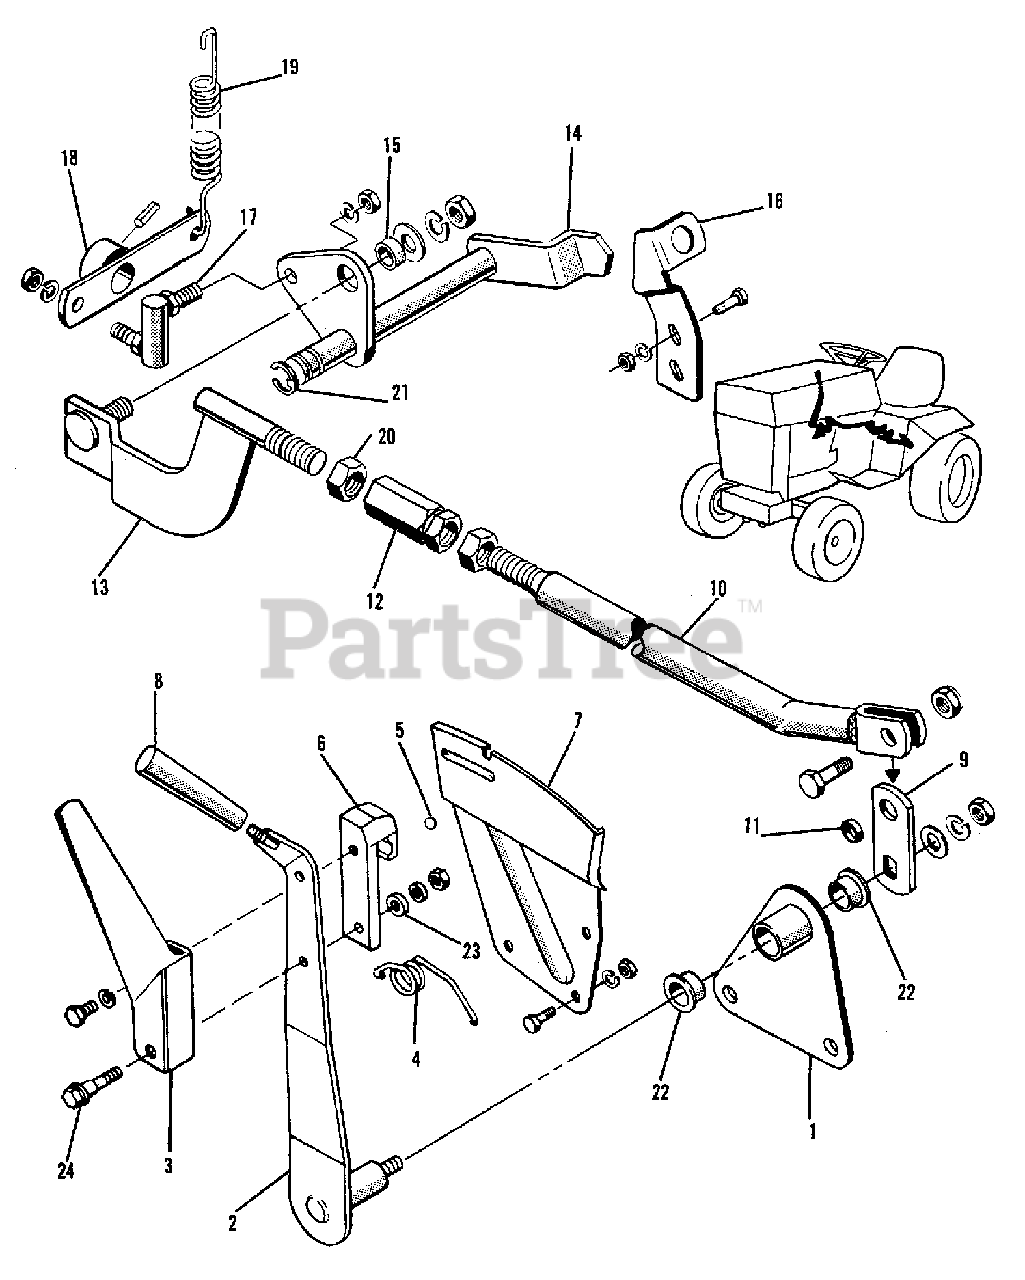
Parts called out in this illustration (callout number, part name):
1	BRACKET ASSEMBLY, Support
2	LEVER ASSEMBLY, Speed Control
2	WASHER, Plain, 3/8
2	LOCKWASHER, 3/8
2	NUT, 3/8 NC
5	BALL, Shift Handle
6	CLAMP, Stop
6	CAPSCREW, 1/4 NC x 1/2
6	LOCKWASHER, 1/4
7	PLATE, Support
7	CAPSCREW, 1/4 NC x 5/8
7	LOCKWASHER, 1/4
7	NUT, 1/4NC
7	WASHER, 9/32 x 5/8 x 18 Ga.
9	CAPSCREW, 3/8NC x 1
9	NUT, Lock, 3/8NC
10	ROD ASSEMBLY, Control (Front)
10	NUT, 1/2NF
12	TURNBUCKLE
13	ROD ASSEMBLY, Control (Rear)
13	WASHER, Plain, 3/8
13	LOCKWASHER, 3/8
13	NUT, 3/8 NC
14	SHAFT ASSEMBLY, Control
16	SUPPORT, Switch
16	CAPSCREW, 5/16NC x 3/4
16	LOCKWASHER, 5/16
16	NUT, 5/16 NC
17	JOIN, Doubl-End Ball
17	LOCKWASHER, 5/16
17	NUT, 5/16 NF
18	LINK ASSEMBLY, Control
18	PIN, Spring, 1/4 x 1-1/4
19	SPRING, Latch
20	NUT, 1/2NF
21	E-RING, (5/8 Diameter Shaft)
22	BUSHING, Flanged
24	BOLT, Shoulder
24	WASHER, 1/4
24	NUT, 1/4NC
